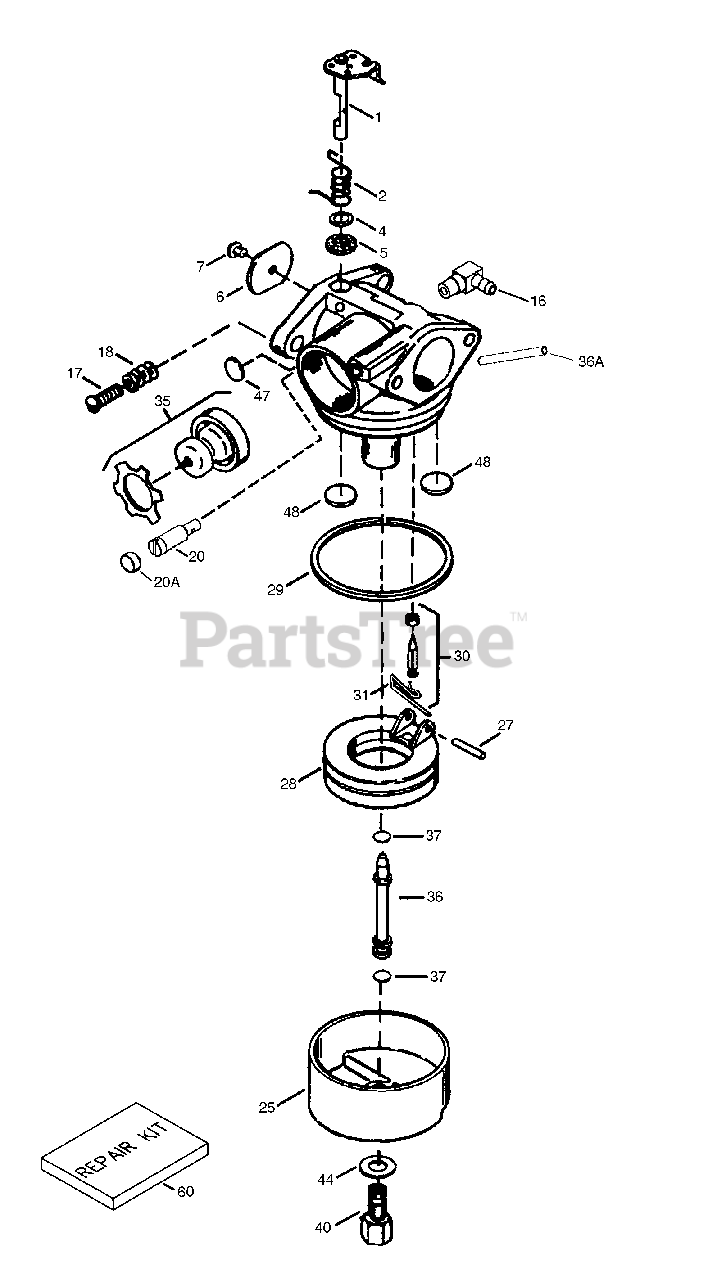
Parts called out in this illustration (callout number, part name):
1	Throttle Shaft & Lever Assembly
2	Throttle Return Spring
4	* Dust Seal Washer
5	* Dust Seal (Throttle)
6	Throttle Shutter
7	* Shutter Screw
16	Fuel Fitting
17	Throttle Crack Screw/Idle Speed Screw
18	Tension Spring
20	Idle Restrictor Screw
20A	Idle Restrictor Screw Cap
25	Float Bowl
27	* Float Shaft
28	Float (Plastic)
29	* Float Bowl "O" Ring
30	* Inlet Needle, Seat, & Clip (Incl. 31)
31	Spring Clip
35	Primer Bulb/Retainer Ring
36	Main Nozzle Tube
36A	Carburetor Tube
37	* "O" Ring, Main Nozzle Tube
40	High Speed Bowl Nut
44	Bowl Nut Washer
47	* Welch Plug, Idle Mixture Well
48	* Welch Plug, Atmospheric Vent
60	Repair Kit (Incl. items marked P)
